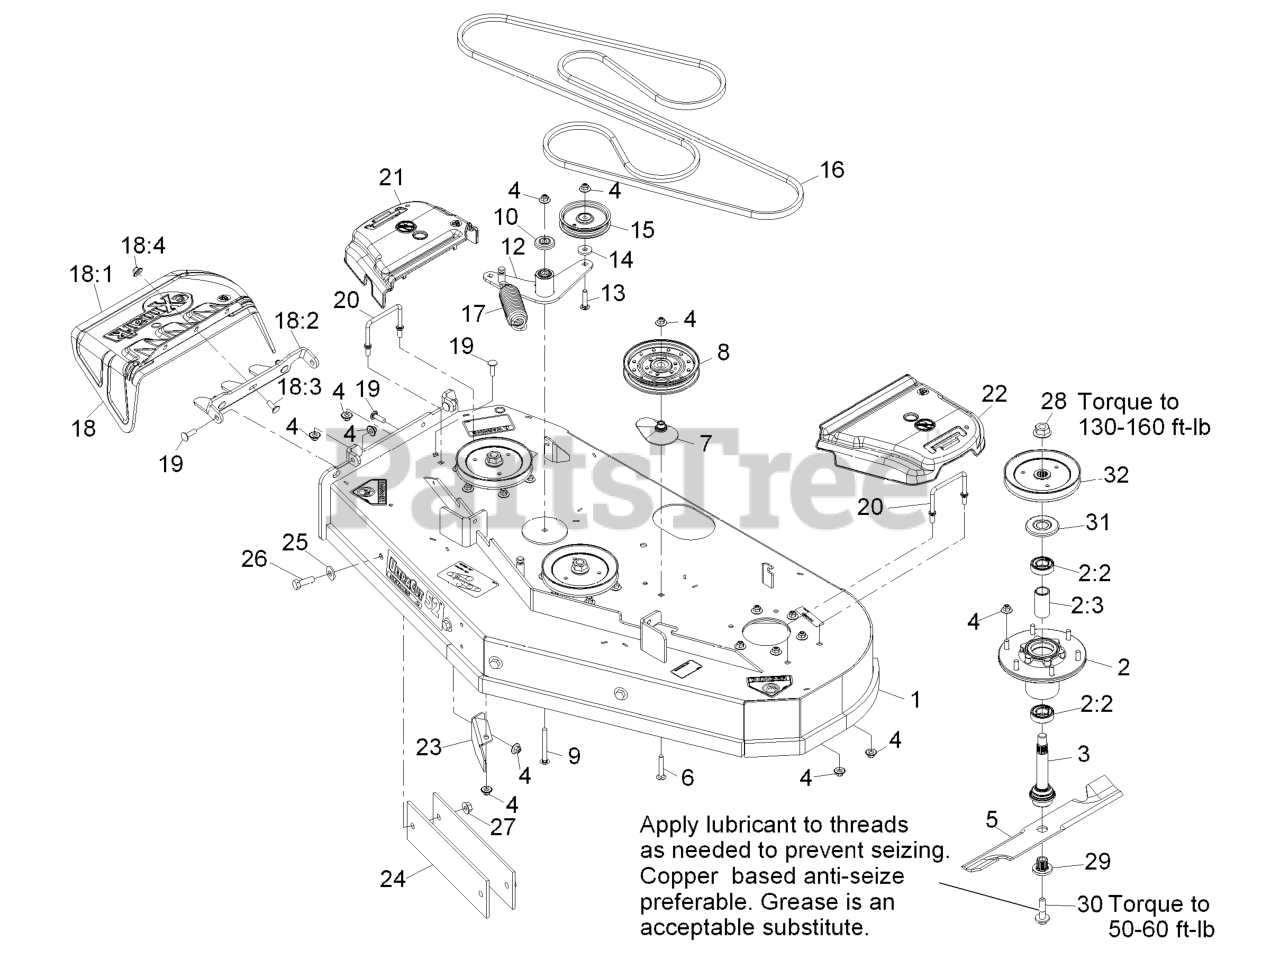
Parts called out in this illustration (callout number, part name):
1	DECK ASM-524
2	ASM-CUTTER HSG WITH BEARINGS
2:2	BEARING-BALL
2:3	SPACER-BEARING
3	ASM-SPINDLE AND SEAL
4	Nut-Nyloc 3/8-16 Flg
6	Bolt-Carriage 3/8-16 X 2 1/4
7	SPACER-PULLEY
9	SCREW-CARR
10	GUARD-TOP
12	IDLER ARM ASM W/BEARINGS
13	SCREW-CARR SPECIAL
15	PULLEY-IDLER
16	BELT-V
18	ASM,DISCHARGE CHUTE
18:1	CHUTE,DISCHARGE
18:2	BRACKET,DISCHARGE CHUTE
18:3	SCREW-CARR
18:4	Nut-Nyloc 3/8-16 Flg
19	Bolt-Carriage 3/8-16 X 1 1/4
20	WIREFORM-COVER
21	COVER-BELT, RH
22	COVER-BELT, LH
23	BAFFLE,DISCHARGE 52/60
24	BAR,WEIGHT
25	WASHER-SPRING
26	SCREW-HH
27	NUT-HHF
28	NUT-FLANGE
29	BUSHING,SPLINED
30	SCREW,SEMS 1/2-20 X 2.19
31	GUARD,BEARING TOP .989
32	SHEAVE,BLADE DRIVE 6.50
